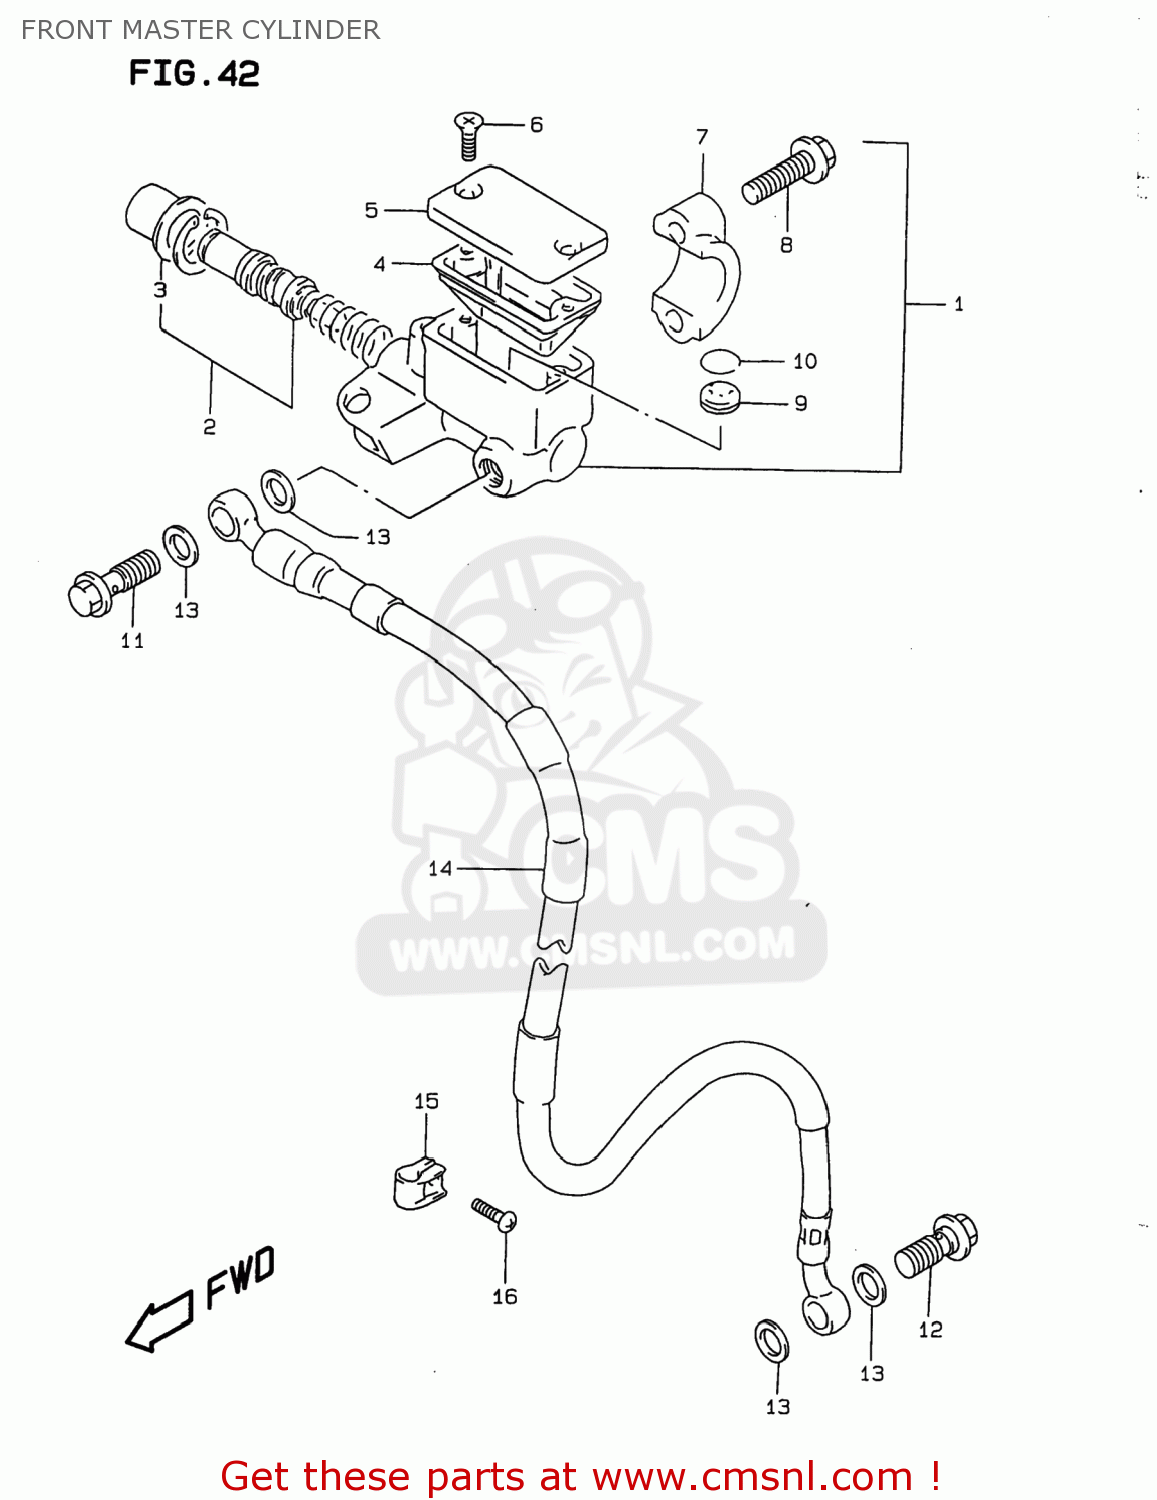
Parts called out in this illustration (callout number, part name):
1	CYLINDER ASSY,FR MASTER
2	PISTON & CUP SET
3	BOOT
4	DIAPHRAGM
5	CAP
6	SCREW
7	HOLDER
8	BOLT
9	SEPARATOR
10	RING
11	BOLT UNION
12	BOLT UNION
13	WASHER(10X15X1.5)
14	HOSE,FR BRAKE
15	CLAMP,BRAKE HOSE
16	SCREW
